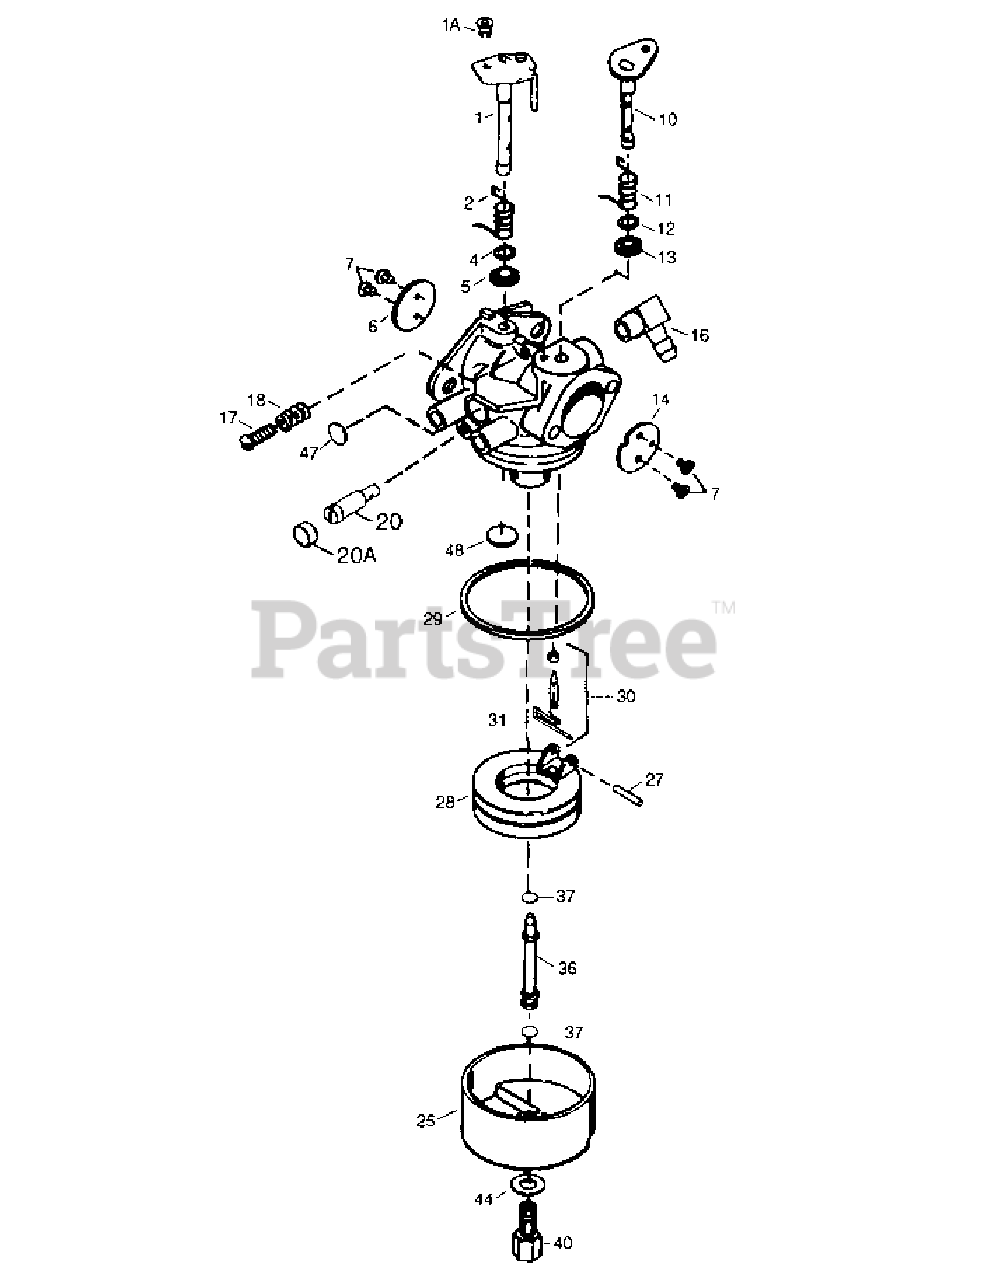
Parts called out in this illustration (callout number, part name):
1	Throttle Shaft & Lever Assembly
2	Throttle Return Spring
6	Throttle Shutter
7	Shutter Screw
10	Choke Shaft & Lever Assembly
14	Choke Shutter
15	Choke Positioning Spring
16	Fuel Fitting
17	Throttle Crack Screw/Idle Speed Screw
18	Tension Spring
20	Idle Restrictor Screw
20A	Idle Restrictor Screw Cap
25	Float Bowl (no drain)
25	Float Bowl Assembly (Incl. 32 & 33)
27	Float Shaft
28	Float (Plastic)
29	Float Bowl "O" Ring
30	Inlet Needle, Seat, & Clip (Incl. 31
31	Spring Clip
32	Bowl Drain Assembly
33	Drain Plunger Gasket
36	Main Nozzle Tube
37	O Ring, Main Nozzle Tube
40	High Speed Bowl Nut
44	Bowl Nut Washer
47	Welch Plug, Idle Mixture Well
48	Welch Plug, Atmospheric Vent
60	Repair Kit, Carb
